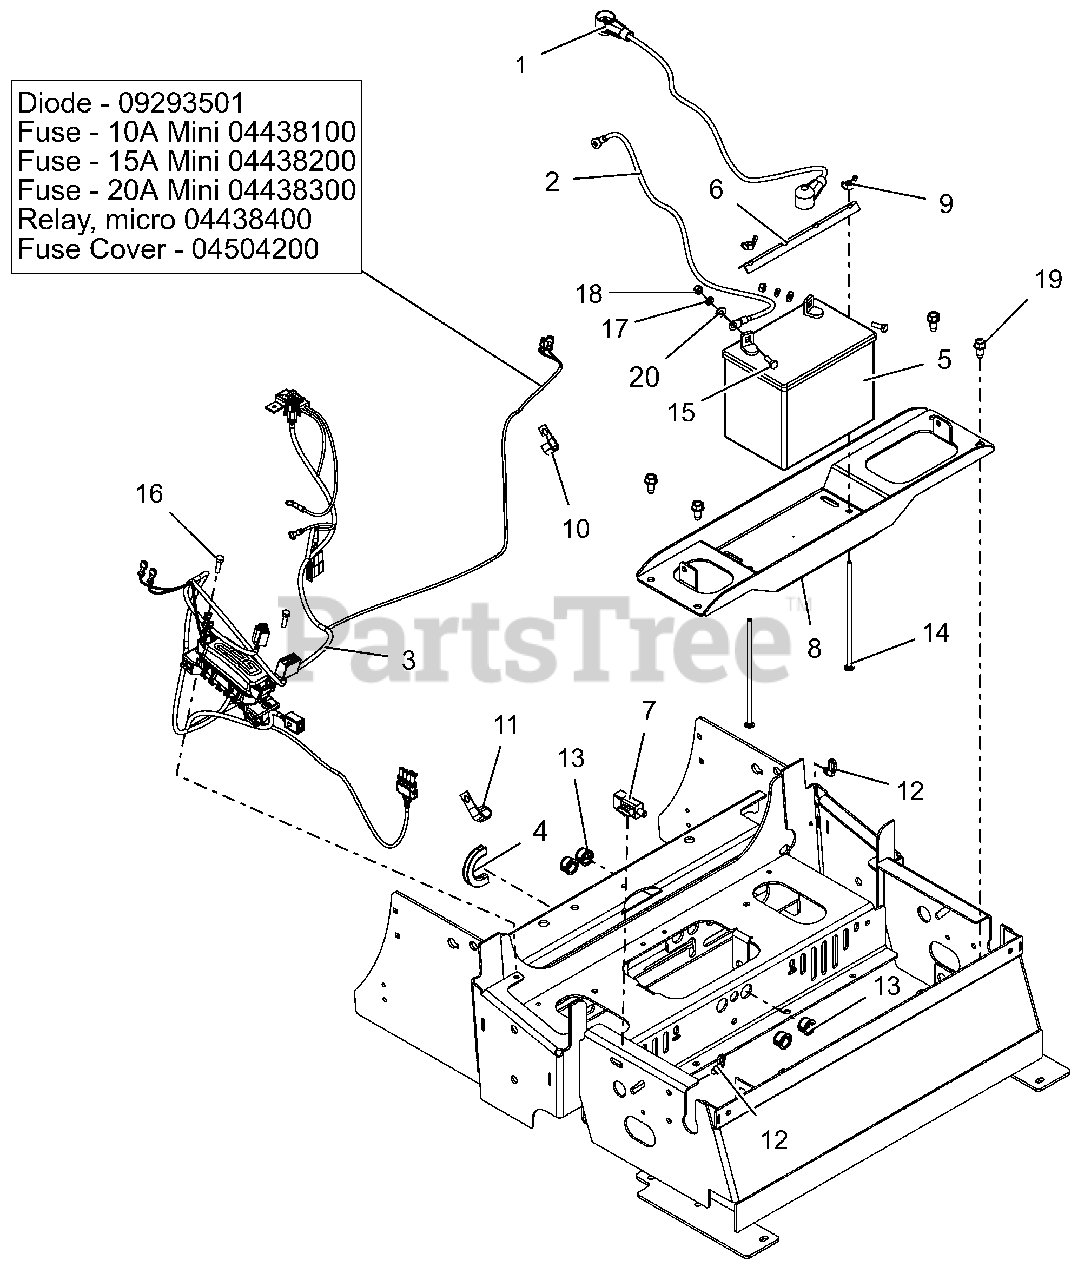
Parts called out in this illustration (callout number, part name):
1	CABLE - POS BATT W/BOOTS 6X35
2	CABLE-NEGATIVE BATTERY 35.00"
3	HARNESS, PT400 WIRING
3	DIODE, CONNECTOR SHELL
3	FUSE,10 AMP MINI-ATC
3	FUSE,15 AMP MINI-ATC
3	FUSE,20 AMP MINI ATC
3	RELAY,MICRO5 TERML W/RESISTOR
3	COVER, HARNESS FUSE/RELAY MOD
4	STRIP, COWL
5	BATTERY, 300 CCA 10U1L
6	HOLD DOWN
7	SWITCH, SNAP IN - N.O./N.O.
8	PT400 GAS BATTERY TRAY - RED
9	NUT-LK WING .250-20 YWZC
12	CABLE TIE W/ TREE (.25 HOLE)
13	BUSH, PANEL SNAP .687X.875X.56
14	BLT-RDHDSQNK .25-20X7.50 GR2YZ
15	@BLT-HEX .25-20X.75 GR5 YWZC
16	@BLT-HEX M6-1.0X25 YWZC
17	@WSHR-LK .25X.062 REG YWZC
18	@NUT-HEX .25-20 YWZC
19	@SCR-TAP .38-16X.75 HWH TR YWZ
20	@WSHR-FL-STL.281X.62X.065 YWZC
